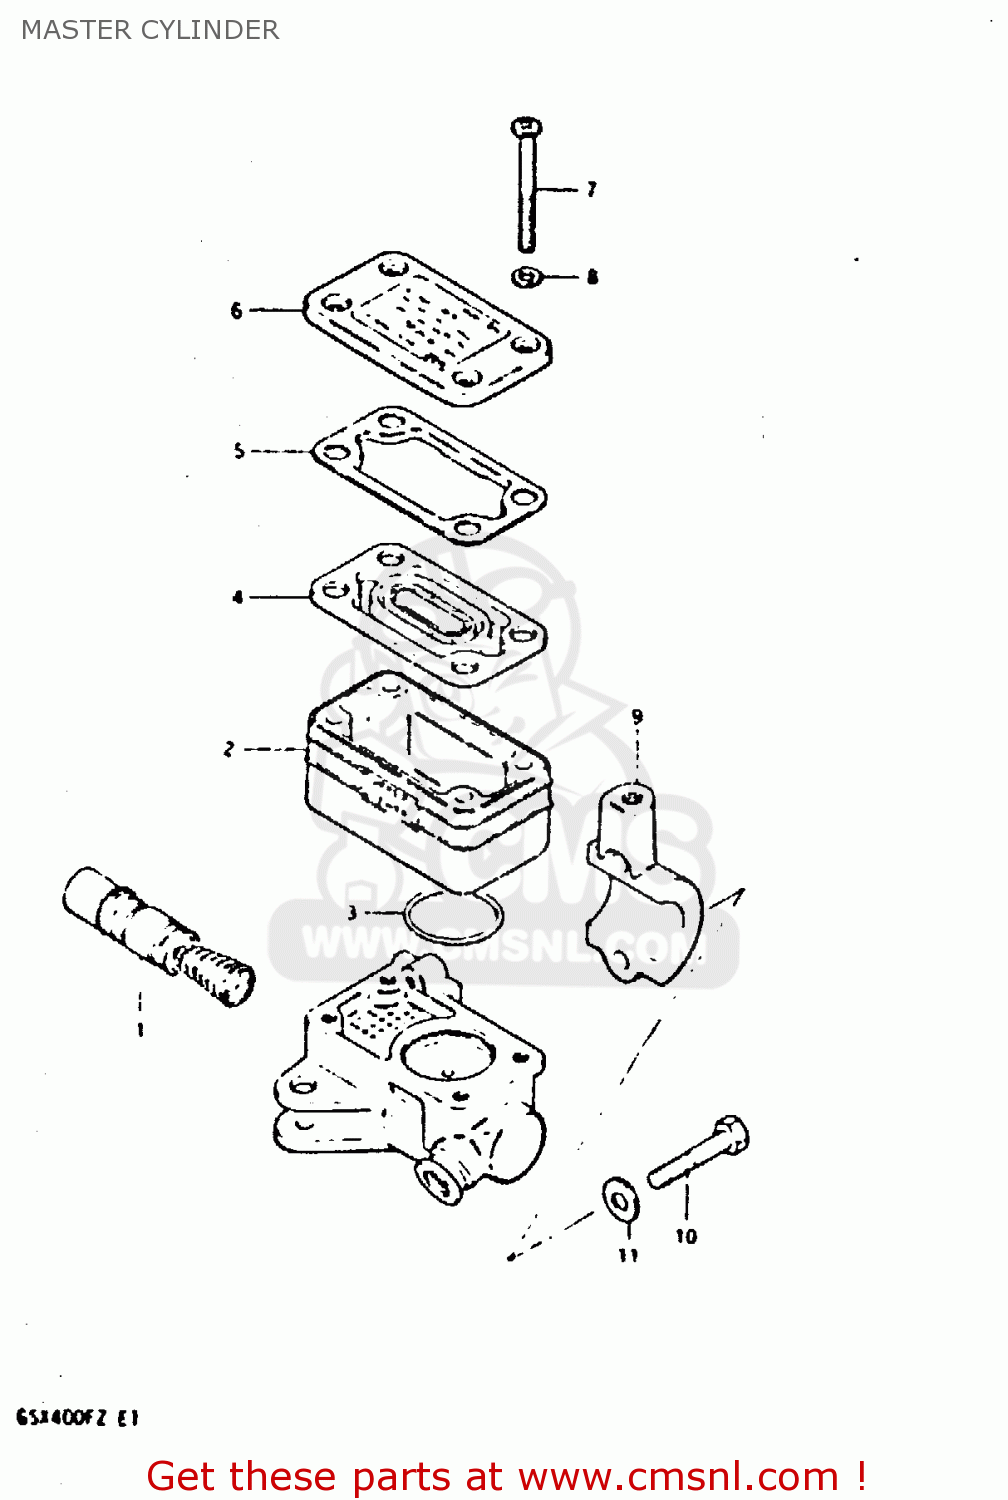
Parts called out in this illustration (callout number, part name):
1	PISTON & CUP SET
2	RESERVOIR
3	O RING
4	DIAPHRAGM
5	PLATE,DIAPHRAGM
6	CAP
7	SCREW
8	WASHER
9	HOLDER
10	BOLT
11	WASHER
